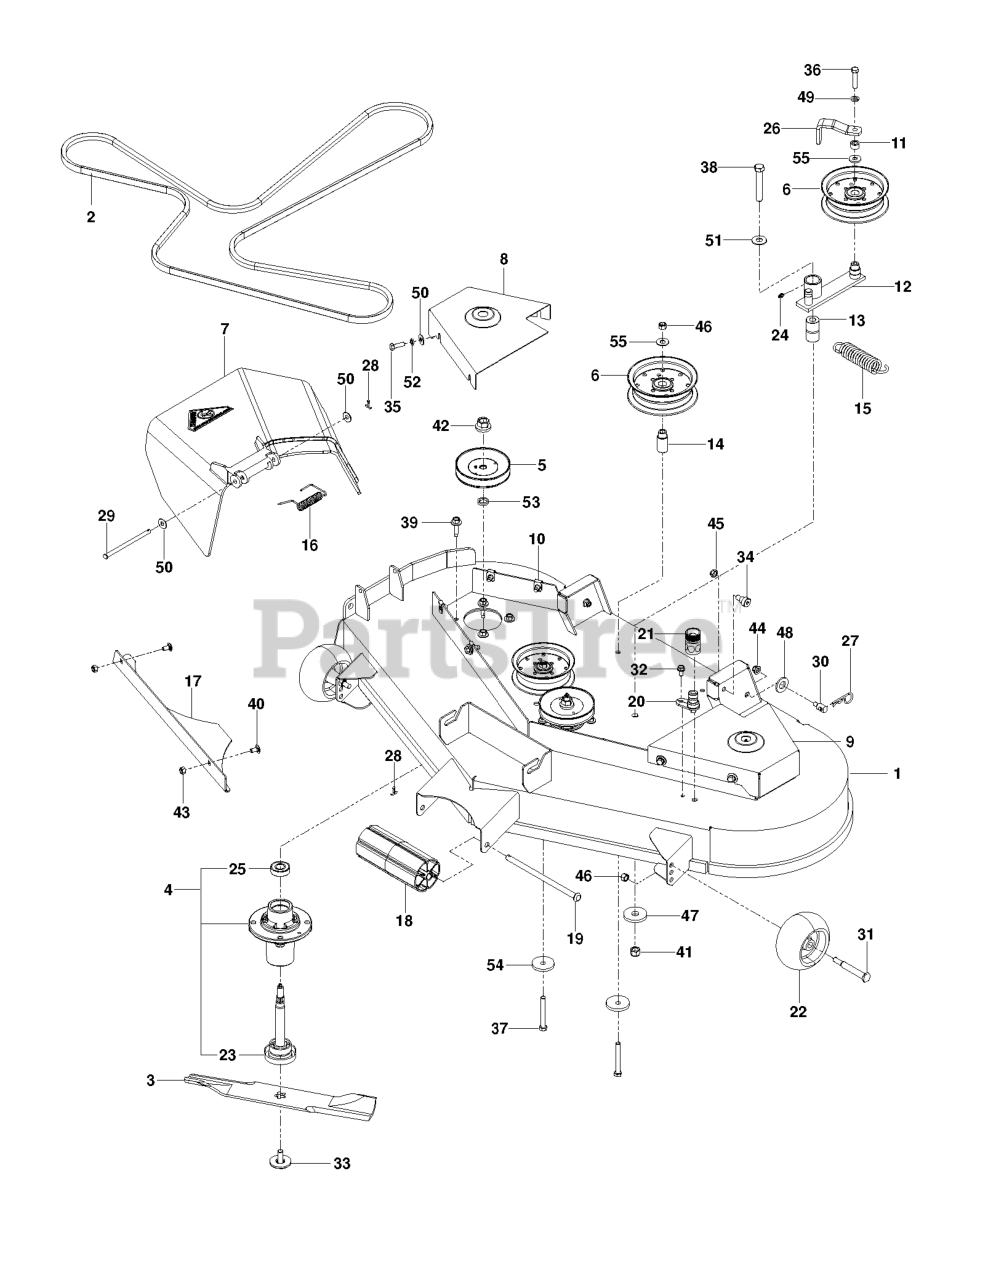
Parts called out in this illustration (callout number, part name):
1	DECK.48".TRI-FORCE.W/DECALS.OR
2	BELT, DECK
3	BLADE, 16-1/4"
4	MANDREL.DECK.ASSEMBLY
5	MANDREL PULLEY
6	PULLEY, IDLER
7	DISCHARGE CHUTE 48"
8	BELT SHIELD - R.H. ORANGE
9	BELT SHIELD - L.H. ORANGE
10	U-CLIP 5/16-18 NUT RETAINER
13	PIVOT BUSHING
14	IDLER BUSHING
16	SPRING - TORSION
17	CONFINEMENT PLATE 48" BLK
18	NOSE ROLLER 48"
19	ROD.ROLLER.NOSE.NARROW.48"
20	PORT.WASHOUT
21	COUPLING.QUICK CONNECT
22	GAUGE WHEEL
23	GREASABLE MANDREL SHAFT
24	ZERK
25	BEARING, BALL
26	GUIDE, BELT
27	HAIRPIN #4
28	RP_COTTER PIN 1/8 X 3/4
29	PIN-CLEVIS 5/16 DIA X 5.19 ZD
30	STUD.FASTNER.W/ANTI-ROTATE
31	SHOULDER BOLT 1/2X2-5/8 ZD SPE
32	BOLT 1/4-20 X 1/2 HWST
33	BOLT.WASHER.ASM.7/16-2
34	SB 3/8-16 X 3/8 SKT HD ZD
35	HCS 5/16C X 1
36	HCS 3/8-16 X 1 3/4 GR5
37	HCS 3/8C X 3
38	HCS 1/2C X 3 1/4
39	WASHER HEAD SCREW
40	CARRIAGE BOLT 5/16C X 5/8"
41	NUT 1/2-13 HEX NYLOC ZD
42	LOCKNUT - 9/16
43	NUT 5/16 NYLOC
44	5/16-18 NYLOC FLANGE NUT
45	NUT HEX 3/8-16 NYLON, THIN
46	NUT 3/8-16 NYLOC
47	WASHER, SUPPORT
48	WASHER 5/8 FLAT
49	SLW 3/8 STD
50	WASHER 5/16 FLAT
51	WASHER 1/2 FLAT
52	WASHER.LOCK.HVY.HLCL.SPR.5/16
53	WASHER-SPACER
54	SPINDLE WASHER
55	WASHER 3/8 FLAT
